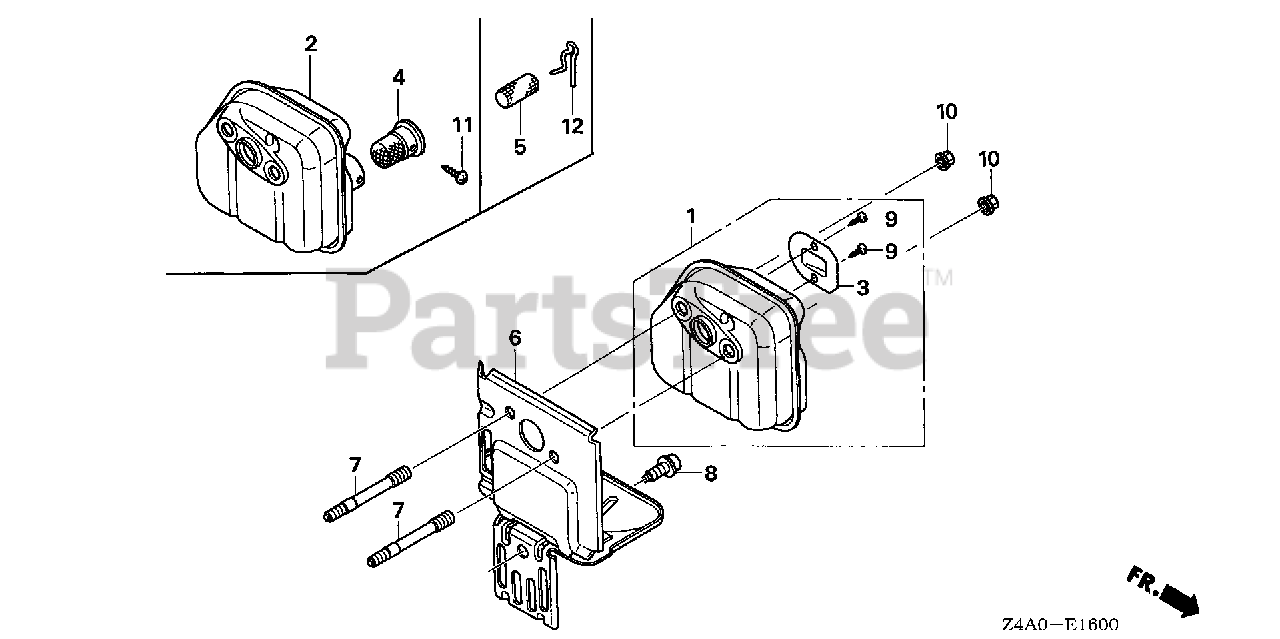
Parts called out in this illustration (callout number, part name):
1	MUFFLER
3	ARRESTER, SPARK
6	GUIDE, AIR EX.
7	BOLT, STUD (5X52)
8	BOLT, SOCKET (5X10) (CT)
9	SCREW, TAPPING (4X6)
10	NUT, SELF-LOCK (5MM)
